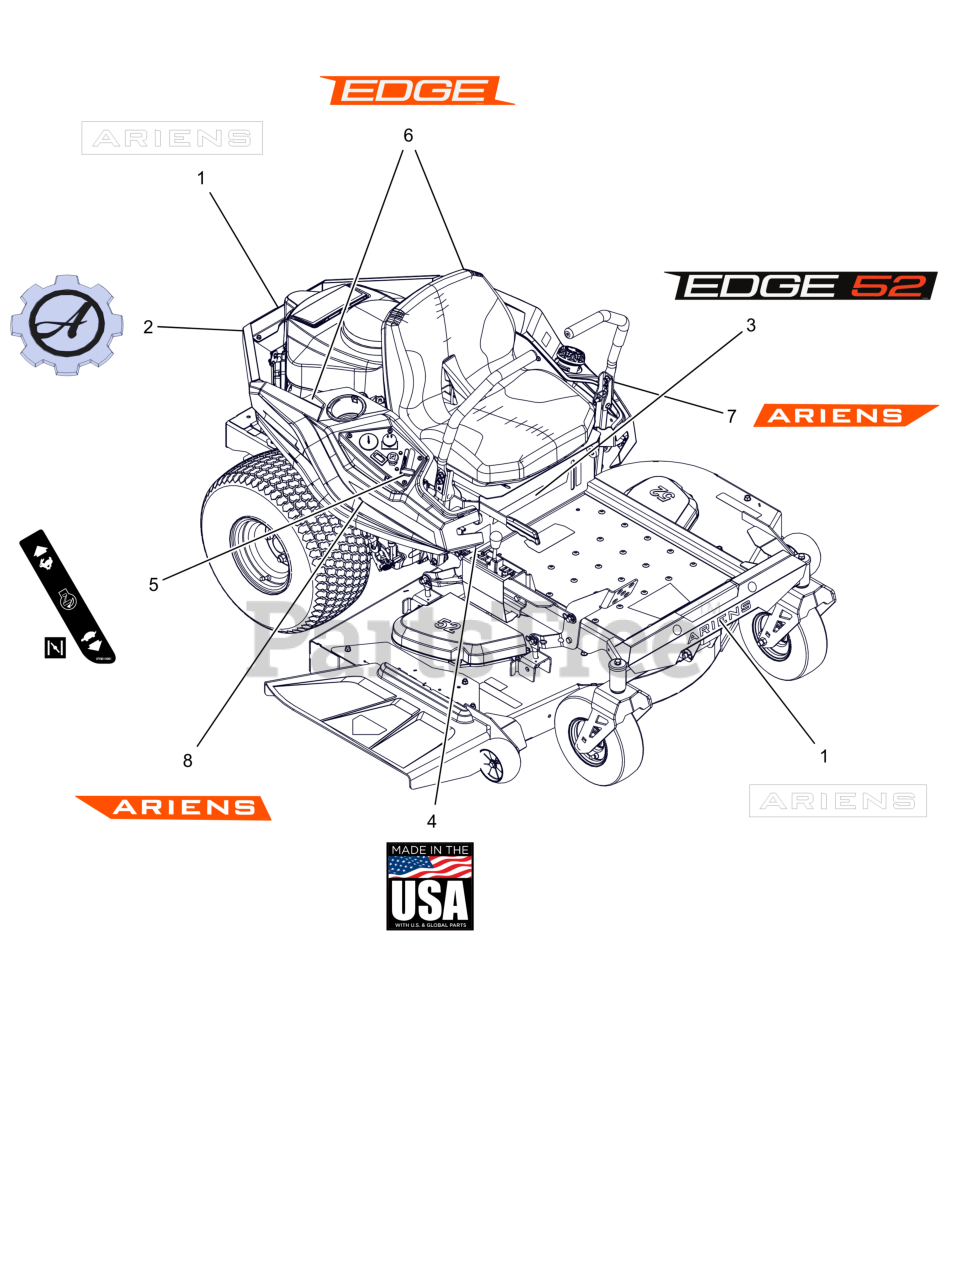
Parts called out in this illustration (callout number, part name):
1	DECAL - ARIENS 9.625"
2	DECAL, ARIENS-GEAR BADGE -THK
3	DECAL, EDGE 52 - KICKPLATE
4	DECAL, MADE IN USA
5	DECAL, SPEED CONTROL
6	DECAL, EDGE FENDER
7	DECAL, ARIENS FENDER LH
8	DECAL, ARIENS FENDER RH
